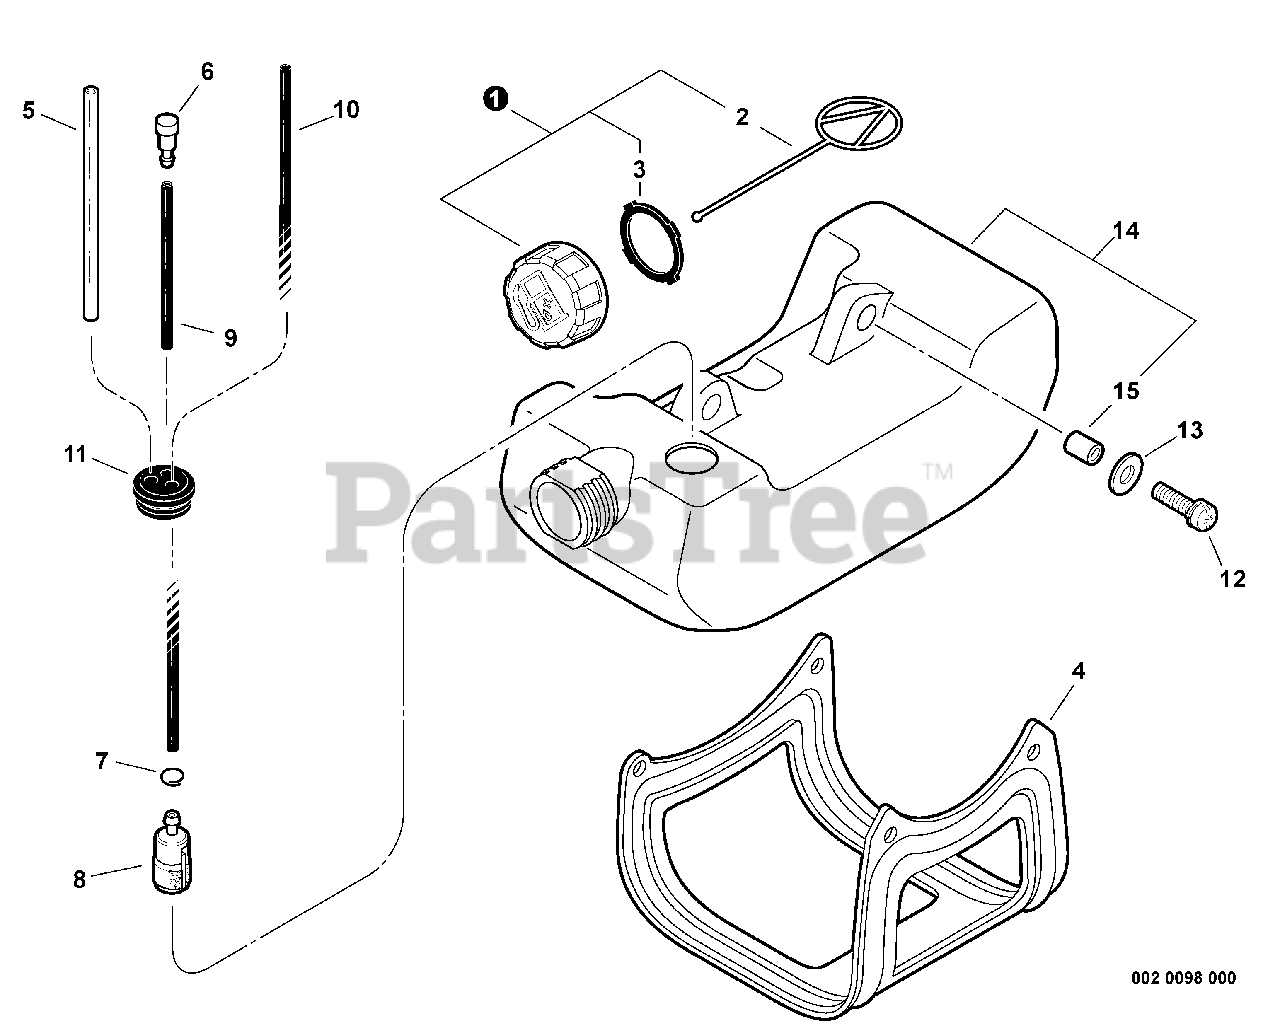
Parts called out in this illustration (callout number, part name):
1	CAP ASSY, FUEL
2	CONNECTOR, CAP
3	GASKET, FUEL CAP
4	GUARD, FUEL TANK
5	PIPE, FUEL RETURN 3×6×90 MM CLEAR
6	VENT ASSY
7	CLIP 6 MM
8	FILTER, FUEL
9	PIPE, FUEL 3x-5x-70 BLACK
10	PIPE, FUEL 3x-5x-180
11	GROMMET, FUEL Ø5
12	SCREW 5×16
13	WASHER 5.5×12×0.8
14	TANK, FUEL
15	SPACER 6.2×7.8×6
